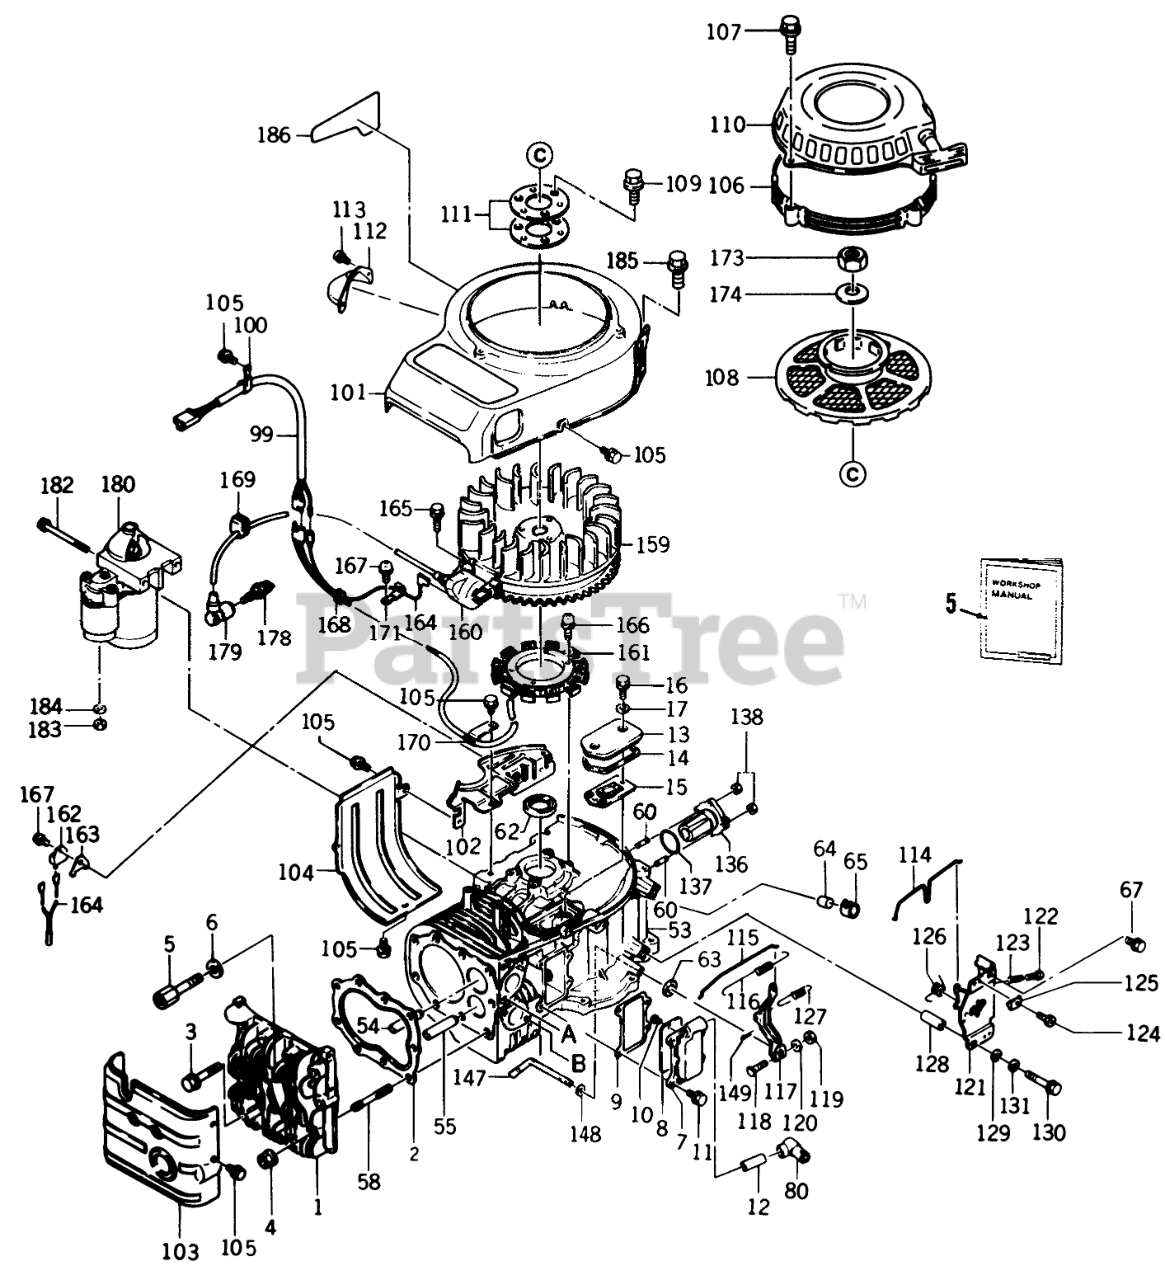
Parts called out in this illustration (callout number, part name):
1	Cylinder Head
2	Gasket-Head
3	Bolt
5	Kawasaki FB460V Workshop Manual
7	Cover-Valve Chamber
11	Bolt-Flanged (6X16)
16	Bolt
53	Crankcase Complete (includes items 54 & 55).
54	Guide-Intake Valve
55	Guide-Exhaust Valve
63	SEAL-OIL (VC6X10X2.6)
67	BOLT-FLANGED (6X10)
101	Fan Housing
102	Fan Housing
105	BOLT-FLANGED (6X10)
107	Bolt-Flanged (6X35)
109	Bolt-Flanged (8X12)
110	Recoil Starter ASM
114	LINK-Choke
115	Link
117	Arm ASM
118	Bolt (6X28)
119	NUT-HEX (6mm)
120	Washer-Plain (6mm)
121	Control Panel Assy (includes items 122, 123,124, 125 & 126)
122	Screw 4 x 25
124	Bolt
131	Lockwasher
136	Shaft
138	Nut
147	Arm-Pivot
148	Washer
149	Pin-Snap (1.2 X 21.2)
159	Flywheel Complete
160	Coil
161	Charging Coil
162	Igniter
164	Lead Wire
165	Bolt
171	Clamp
178	Spark Plug
180	Electric Starter Assy-see section 9-7 for parts breakdown
183	Nut-Hex, Small (8mm)
184	WASHER 5/16 SAE
185	Bolt 6 x 14
